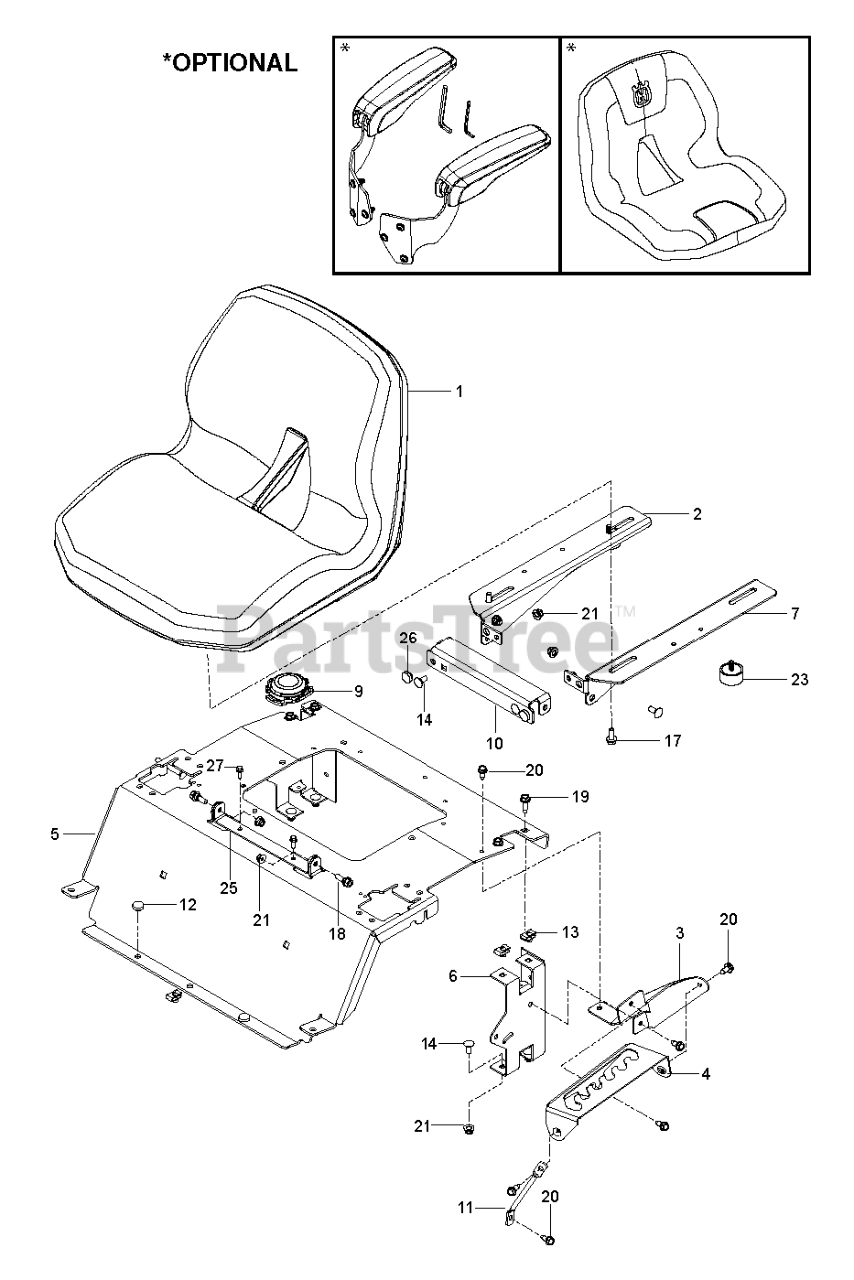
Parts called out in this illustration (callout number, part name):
2	BRACKET SEAT PAN LEFT BLACK X4
3	PLATE.SUPPORT.DECK.LIFT.X431
4	PLATE.DECK.LIFT.X431
5	PLATE SEAT SUPPORT; RZ ORANGE
6	SUPPORT REAR SEAT BLACK
7	BRACKET SEAT PAN RIGHT BLACK X
9	SWITCH.SEAT.DELTA.OPC.
10	BRACKET FRONT SEAT PAN BLACK X
11	SUPPORT.LEG.DECK.LIFT
12	GROMMET.BUMPER
13	U-CLIP 5/16-18 NUT RETAINER
14	BOLT 5/16C X 3/4" CARRIAGE
17	HHFS 5/16-18 X 3/4
18	BOLT, SHOULDER
19	SCREW.THDROL.5/16-18X3/4.TTY
20	BOLT.5/16HEX.WHS.HD
21	5/16-18 NYLOC FLANGE NUT
23	BUMPER 5/16-18
25	BRACKET.SEAT.REINF.X668
26	GROMMET, BUMPER
27	SCREW.FLG.LOCKING.1/4-20X.75
